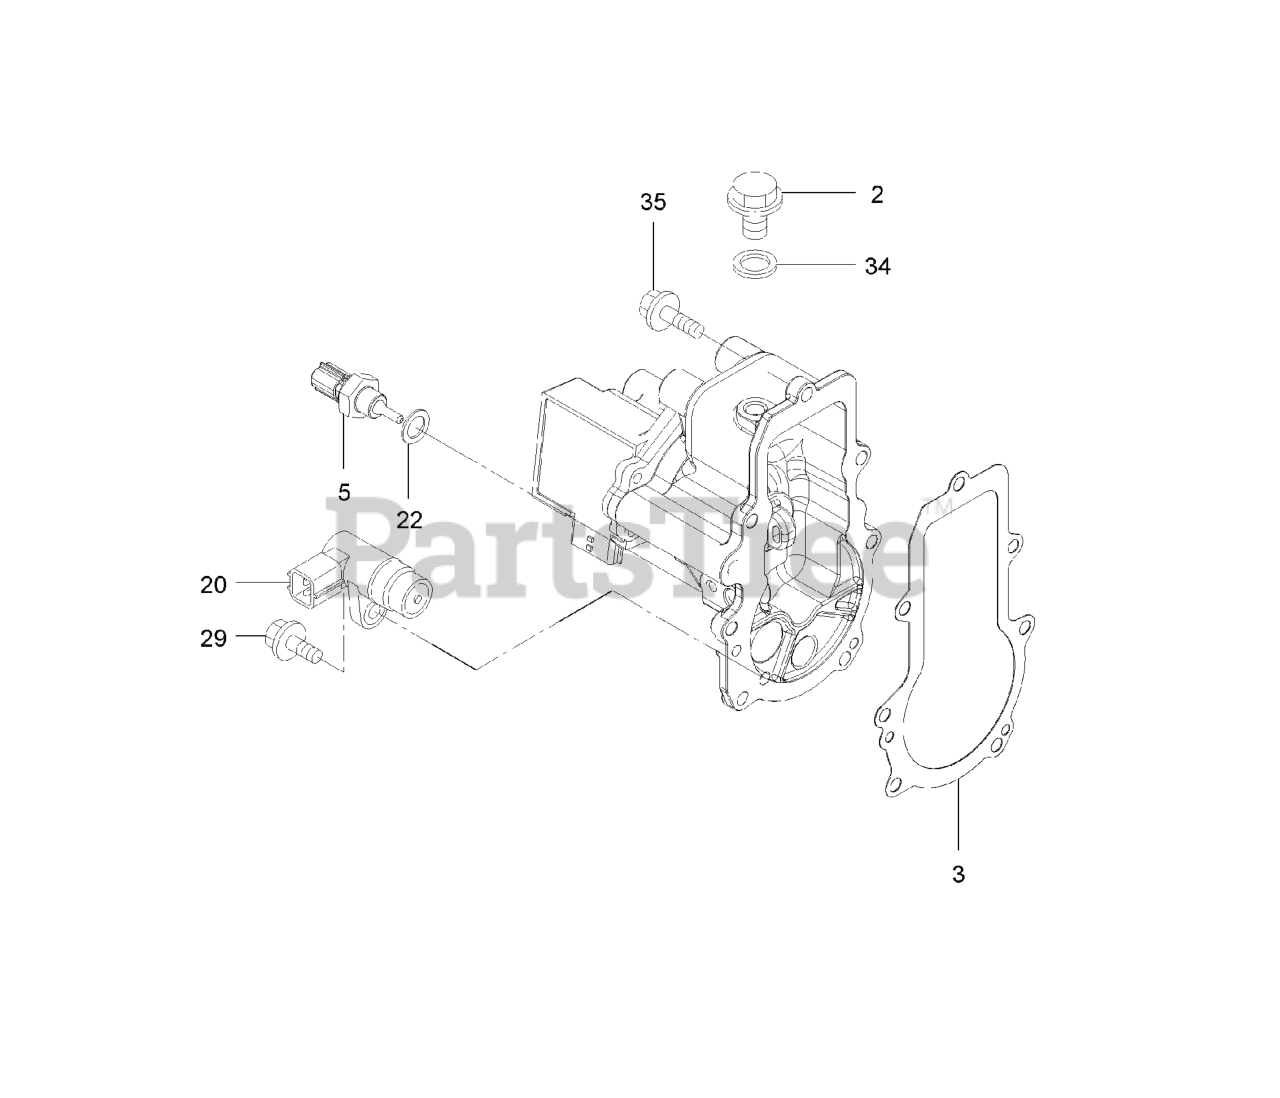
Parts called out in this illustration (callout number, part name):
5	SENSOR-OIL TEMP
22	WASHER-SEAL
34	WASHER-SEAL
